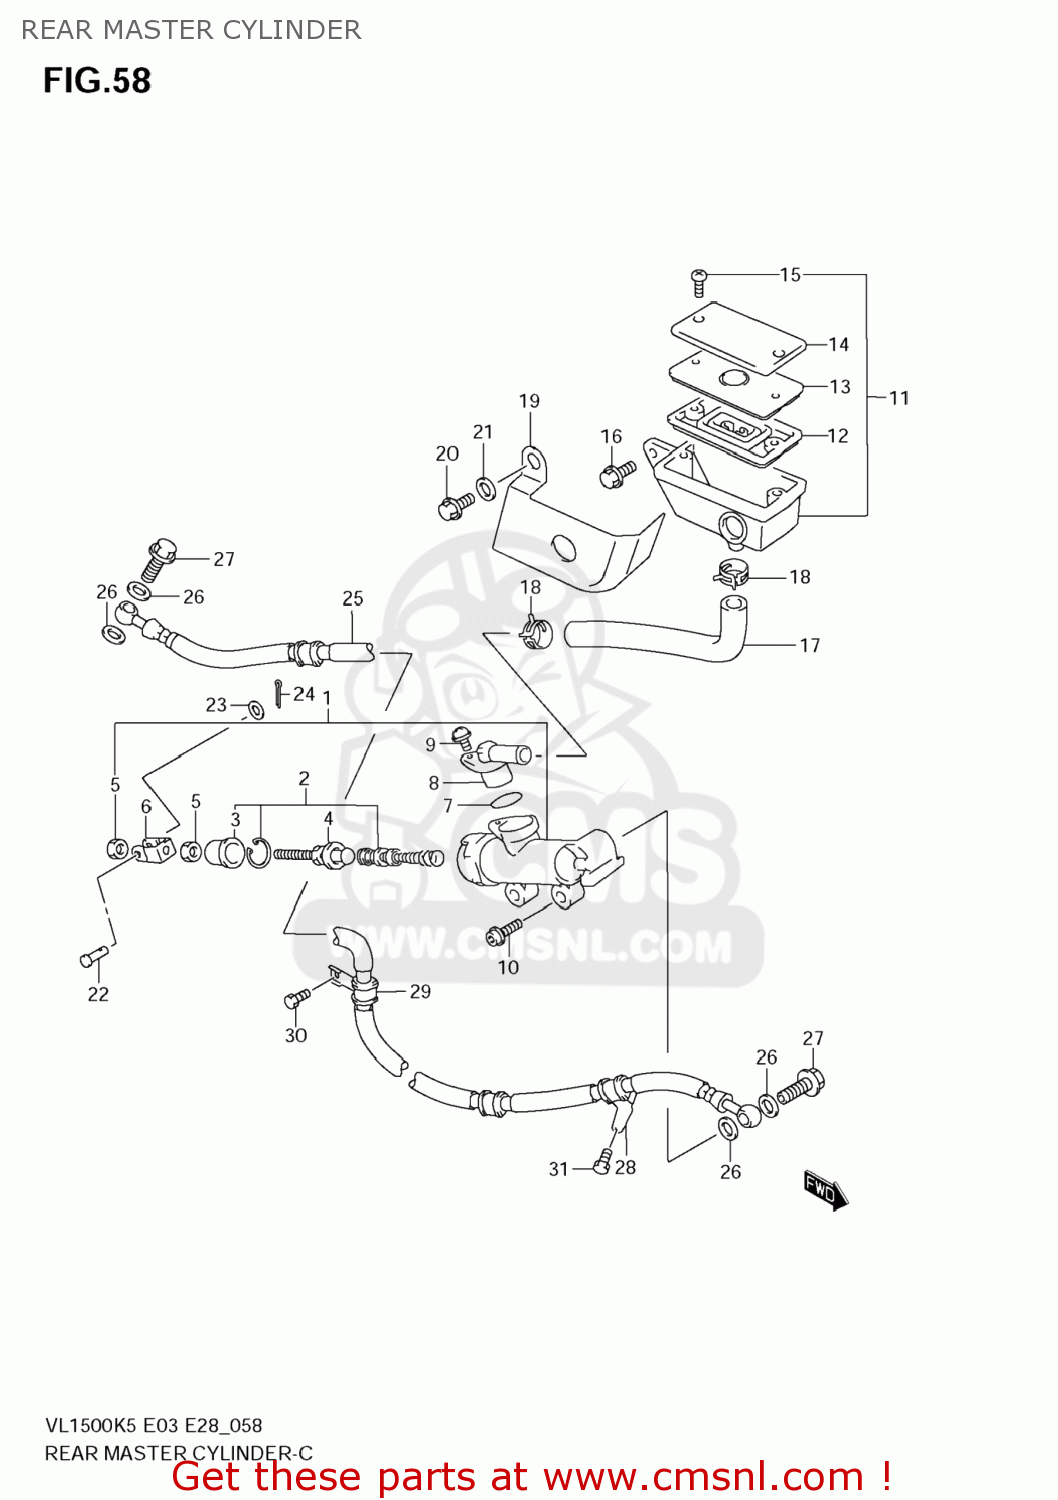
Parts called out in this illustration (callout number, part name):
1	CYLINDER ASSY,RR MASTER
2	PISTON/CUP SET
3	BOOT
4	ROD,PUSH
5	NUT
6	YOKE
7	O RING
8	CONNECTOR
9	SCREW
10	BOLT
11	TANK ASSY,RR RESERVOIR
12	13
13	PLATE,DIAPHRAGM
14	CAP
15	SCREW
16	BOLT
17	HOSE,RESERVOIR TANK
18	CLIP
19	COVER,RESERVOIR TANK
20	BOLT
21	WASHER
22	PIN(6X18.2)
23	WASHER
24	PIN
25	HOSE,RR BRAKE
26	WASHER(10X15X1.5)
27	BOLT UNION
28	CLAMP,RR BRAKE HOSE
29	CLAMP,FRONT BRAKE NO.2
30	BOLT
31	BOLT
